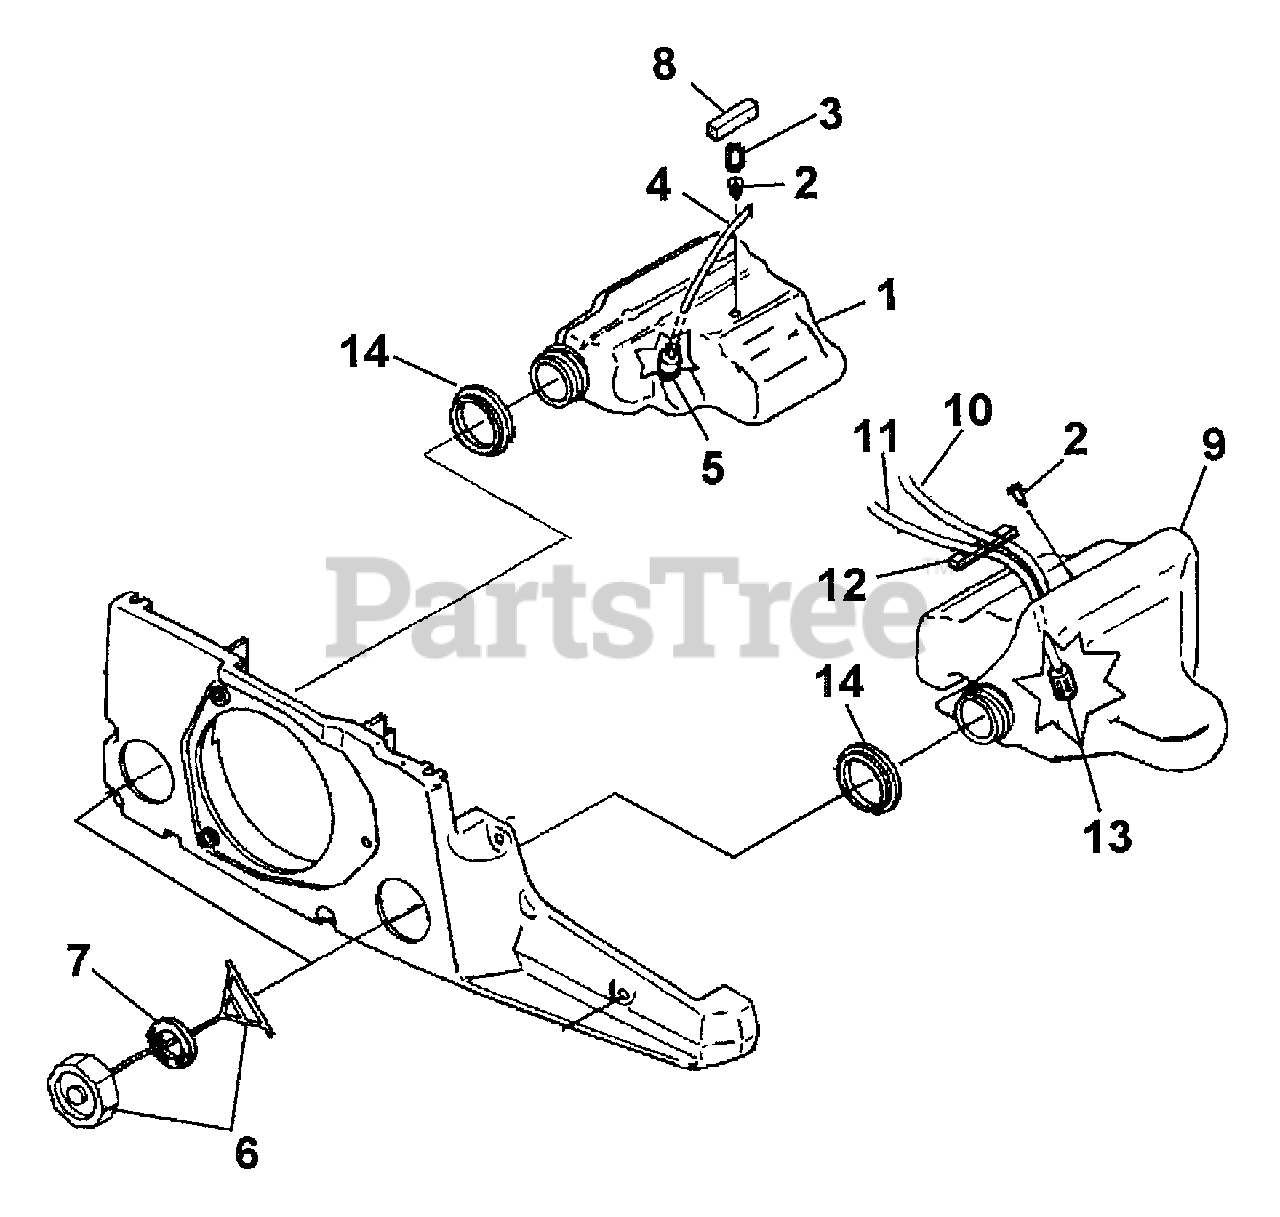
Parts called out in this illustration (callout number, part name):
1	OIL TANK ASSY.
2	VALVE-Check
2	VALVE- Check
3	PIN-Spirol
4	TUBING- Rubber (7 1/4")
5	FILTER- Oil
6	CAP- Tank (w/Retainer)
7	GASKET-Fuel Cap
8	FILTER- Oil Tank Valve
9	FUEL TANK ASSY.
10	TUBING-Rubber (5 1/4")
11	TUBING- Rubber (9")
12	FILTER- Foam
13	FILTER- Fuel
14	SAWDUST SEAL
